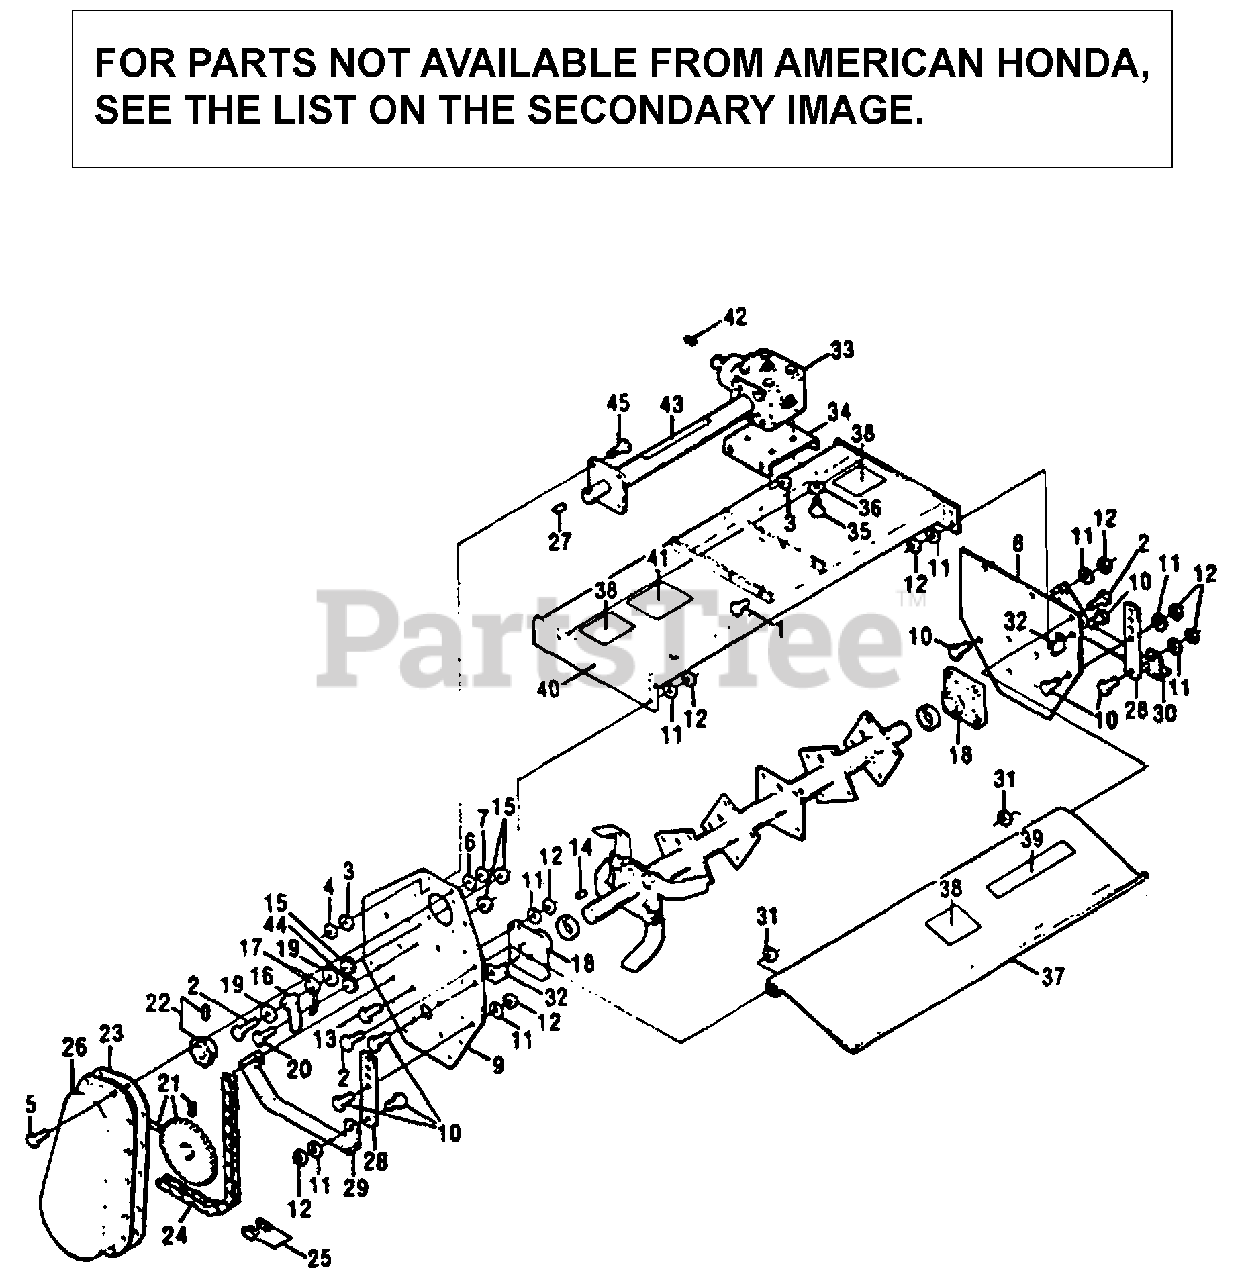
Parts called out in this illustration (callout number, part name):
1	SCREW, CAP (3/8X3/4")
2	SCREW, CAP (3/8X2-1/4")
3	WASHER, LOCK (3/8")
4	NUT, HEX. (3/8")
5	SCREW, CAP (5/16X3/4")
6	WASHER, LOCK (5/16") (NOT AVAILABLE)
7	NUT, HEX. (5/16")
8	PLATE, R. SIDE
9	PLATE, L. SIDE
10	SCREW, CAP (1/2X1-1/4")
11	WASHER, LOCK (1/2") (NOT AVAILABLE)
12	NUT, HEX. (1/2") (13 UNC)
13	SCREW, CAP (1/2X1-1/2") (NOT AVAILABLE)
15	NUT, WHIZ (3/8")
16	TENSIONER, CHAIN
17	SPRING, CHAIN TENSIONER (NOT AVAILABLE)
18	BEARING ASSY.
19	WASHER, FLAT (3/8") (NOT AVAILABLE)
20	SCREW, CAP (3/8X1-3/4") (NOT AVAILABLE)
21	SPROCKET (29-TOOTH)
22	SPROCKET (9-TOOTH) (NOT AVAILABLE)
23	GASKET, CHAIN COVER (NOT AVAILABLE)
24	CHAIN, DRIVE (NOT AVAILABLE)
25	MASTER LINK
26	COVER, CHAIN
28	BAR, DEPTH ADJUSTING
29	SKID SHOE WELD, R.
30	SKID SHOE WELD, L.
31	NUT, LOCK (3/8") (16 UNC)
33	BOX ASSY., GEAR
34	PLATE WELD, GEAR BOX
38	DECAL, DANGER USA
40	FRAME ASSY. (NOT AVAILABLE)
44	NUT, JAM (3/8") (NOT AVAILABLE)
45	SCREW, CAP (3/8X1") (NOT AVAILABLE)
